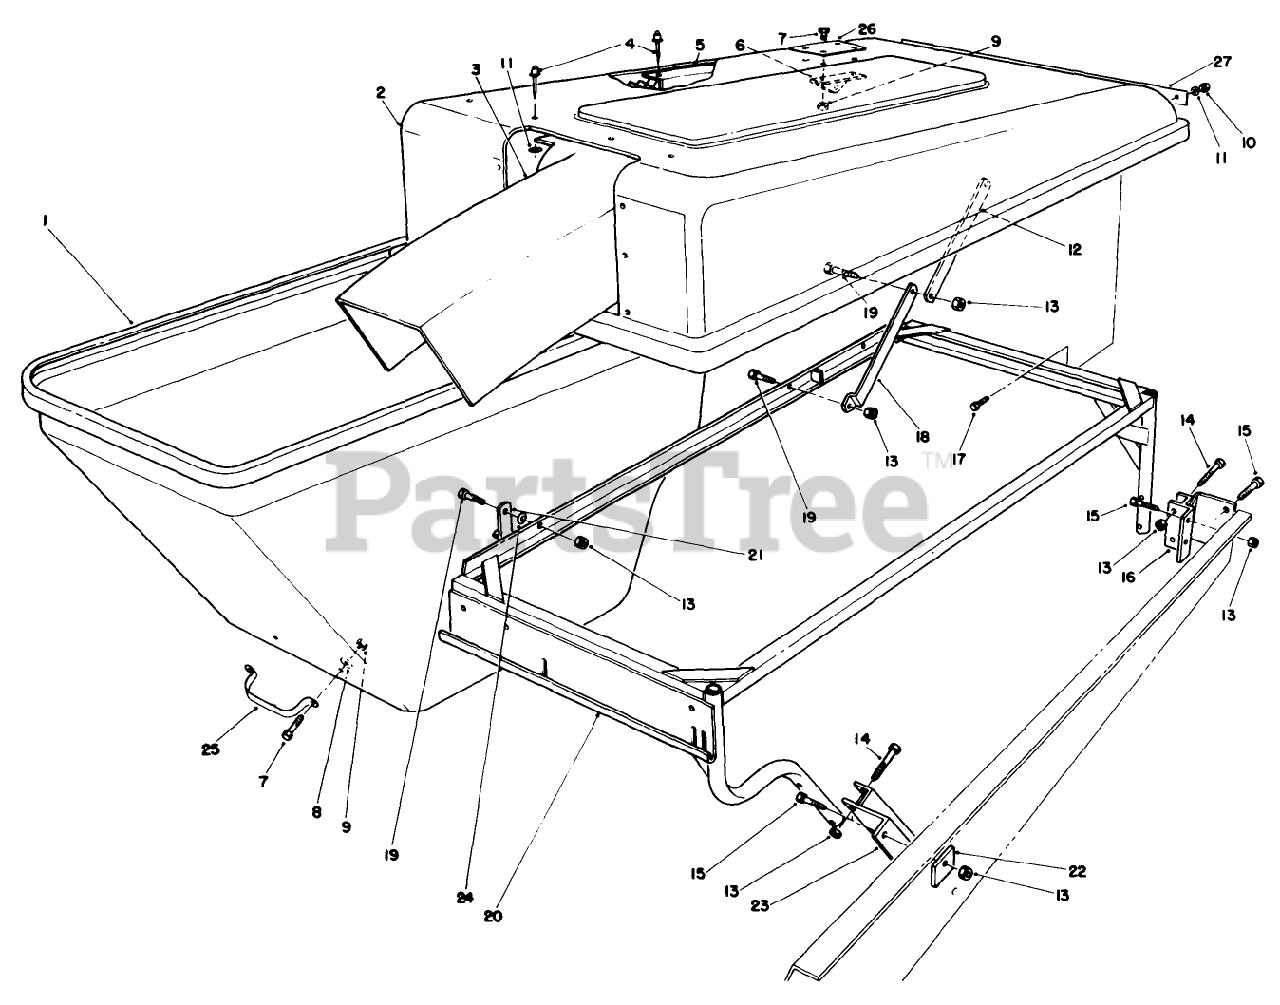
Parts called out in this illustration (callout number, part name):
1	BAGGER HOPPER
2	BAGGER HOOD
3	BAGGER SNOUT
4	RIVET-POP
5	Bagger Screen
6	Pivot
7	SCREW-HH
8	WASHER-FLAT
9	NUT-LOCK, NI
10	NUT-LOCK, NI
11	WASHER-FLAT
12	Link
13	NUT-LOCK, NI
14	SCREW-HH
15	SCREW-HH
16	Bracket-Rear
18	Link-Bag
19	SCREW-HH
20	HOPPER FRAME WA
21	Latch-Hopper
22	Plate-Reinforcing
23	Bracket-Front
24	WASHER-SPRING
25	Handle
26	HOOD PLATE
27	HINGE PLATE
